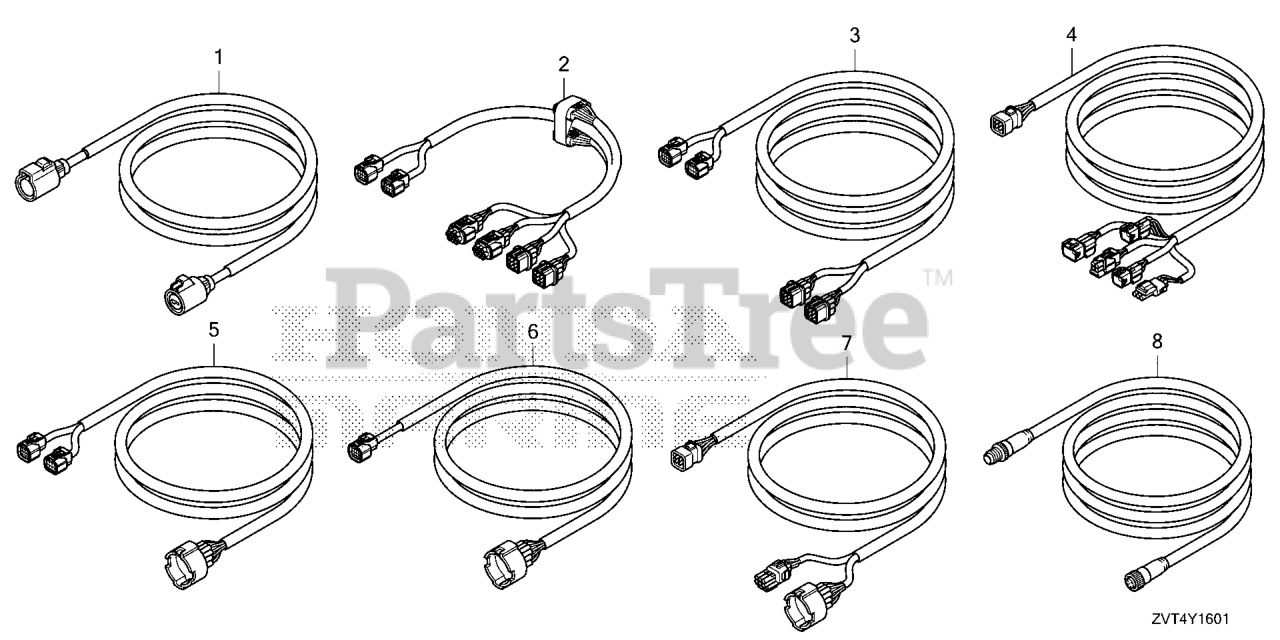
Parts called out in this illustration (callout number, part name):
1	WIRE ASSY., EXTENSION POWER
2	CABLE ASSY., BRANCH
3	CABLE ASSY., TRUNK (18FT) (DBW)
3	CABLE ASSY., TRUNK (24FT) (DBW)
3	CABLE ASSY., TRUNK (30FT) (DBW)
5	CABLE ASSY., ENGINE DROP (SINGLE 6FT)
5	CABLE ASSY., ENGINE DROP (SINGLE 16FT)
5	CABLE ASSY., ENGINE DROP (SINGLE 20FT)
5	CABLE ASSY., ENGINE DROP (SINGLE 25FT)
5	CABLE ASSY., ENGINE DROP (SINGLE 30FT)
6	CABLE ASSY., ENGINE DROP (6FT)
6	CABLE ASSY., ENGINE DROP (10FT)
6	CABLE ASSY., ENGINE DROP (14FT)
8	CABLE ASSY., NETWORK (6FT)
8	CABLE ASSY., NETWORK (16FT)
8	CABLE ASSY., NETWORK (32FT)
8	CABLE ASSY., NETWORK (49FT)
